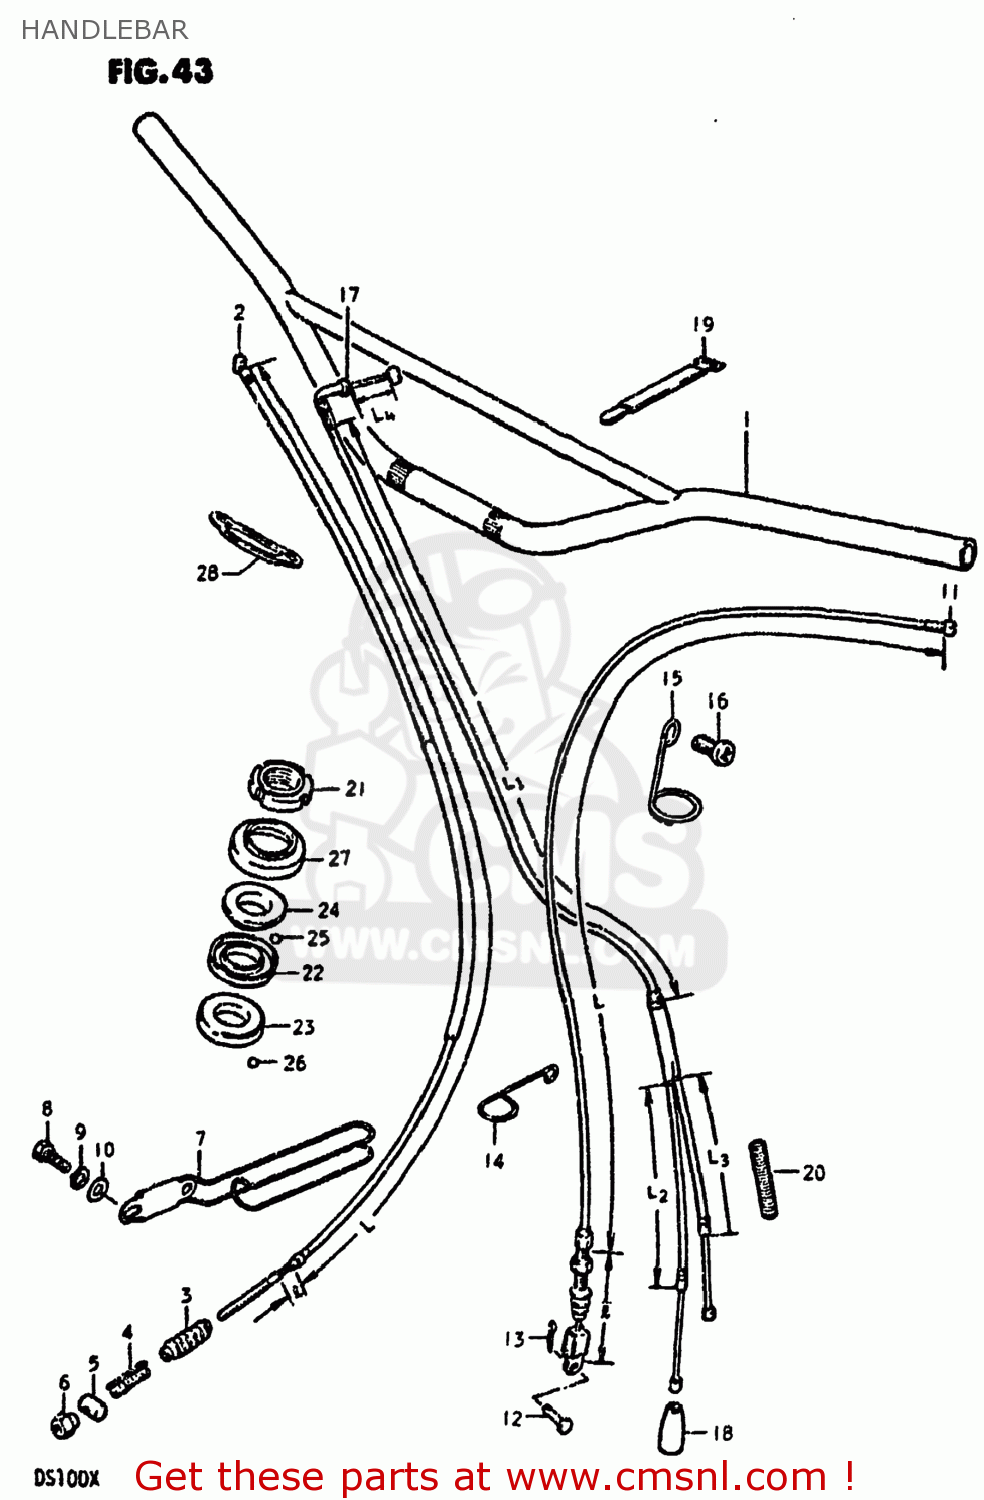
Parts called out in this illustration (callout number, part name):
1	HANDLEBAR
2	CABLE ASSEMBLY,FRONT BRAKE
3	SEAL,DUST(7X16X75)
4	SPRING
5	PIN,10X19
6	NUT
7	GUIDE,CABLE
8	BOLT 8X12
9	LOCK WASHER
10	WASHER
11	CABLE ASSEMBLY,CLUTCH
12	PIN(L:15)
13	PIN
14	CLAMP
15	CLIP
16	SCREW
17	CABLE ASSY,THROTTLE
18	SEAL,DUST(7X18X30)
19	CLAMP L:110
20	PROTECTOR,CABLE
21	NUT,STEERING STEM(25X44X10)
22	RACE,STEERING INNER UPR
23	LACE,STEERING INNER LWR
24	RACE,STEERING OUTER UPR
25	BALL
26	BALL
27	DUST SEAL,STEERING UPR
28	GUIDE,CABLE
